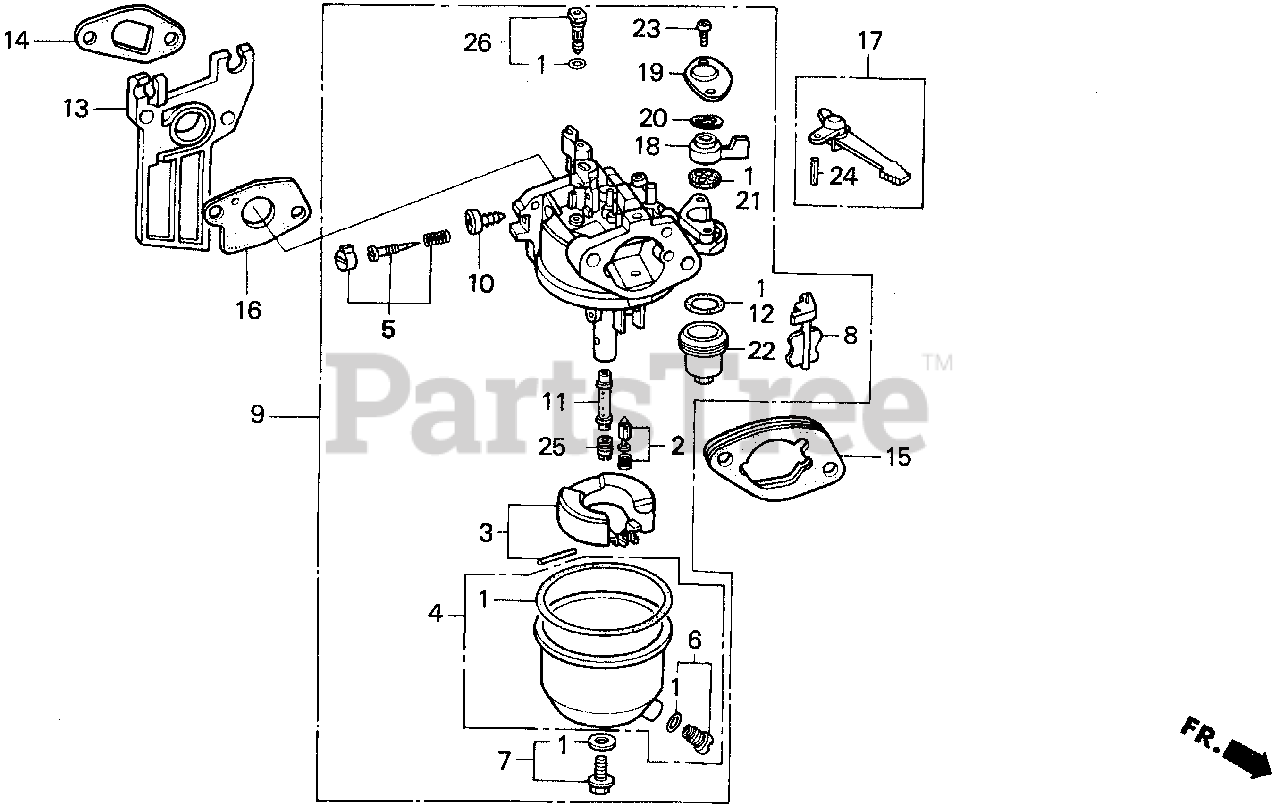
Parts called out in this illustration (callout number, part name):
1	GASKET SET
2	VALVE SET, FLOAT
3	FLOAT SET
4	CHAMBER SET, FLOAT
5	SCREW SET
6	SCREW SET, DRAIN
7	SCREW SET B
9	CARBURETOR ASSY. (BE60C B)
10	SCREW, THROTTLE STOP
11	NOZZLE, MAIN
12	GASKET, FUEL STRAINER CUP
13	INSULATOR, CARBURETOR
14	GASKET, INSULATOR
15	SPACER, CARBURETOR
16	GASKET, CARBURETOR
17	LEVER, CHOKE (STD)
18	LEVER, VALVE
19	PLATE, LEVER SETTING
20	SPRING, VALVE LEVER
21	GASKET, VALVE
22	CUP, FUEL STRAINER
23	SCREW, PAN (3X8)
24	PIN, SPRING (2X12)
25	JET, MAIN (#58)
25	JET, MAIN (#60)
25	JET, MAIN (#62)
26	JET SET, PILOT (#35)
